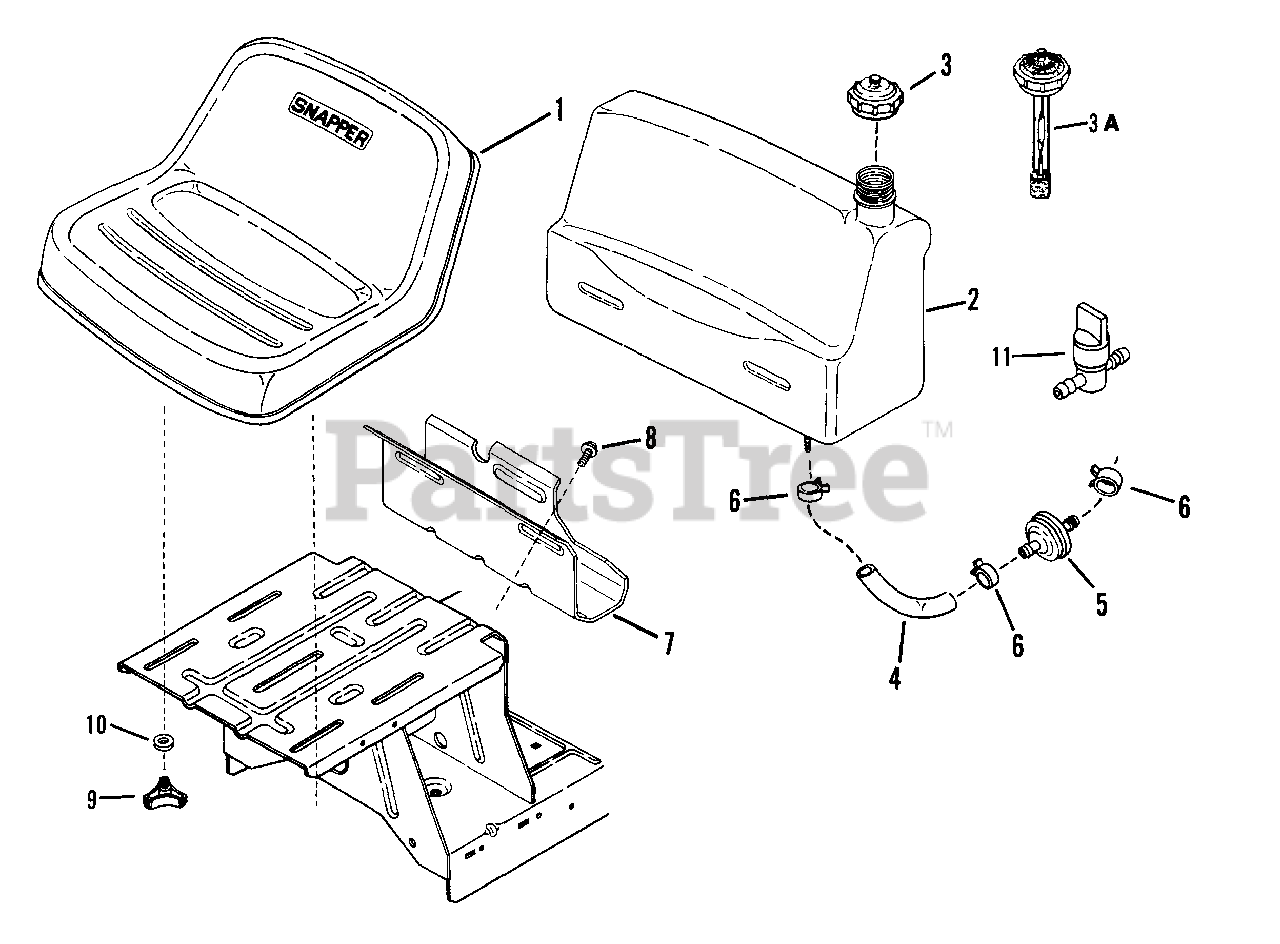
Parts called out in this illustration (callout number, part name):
1	SEAT, Operator
2	ASSEMBLY, Fuel Tank
3	CAP, Fuel Tank
3A	CAP, Fuel Tank/with Gauge
4	HOSE, Fuel (7" Long)
4	HOSE, Fuel (5" Long)
4	HOSE, Fuel (8-1/2" Long)
4	HOSE, Fuel (24-1/4" Long)
5	FILTER, Fuel (In-Line)
6	CLAMP, Fuel Line
7	BRACKET, Fuel Tank (Rear)
8	SCREW, 5/16-18 x 5/8" Self-Tapping
9	KNOB, Seat adjusting
10	WASHER, 5/16 Flat
11	VALVE, Fuel Shut-Off
